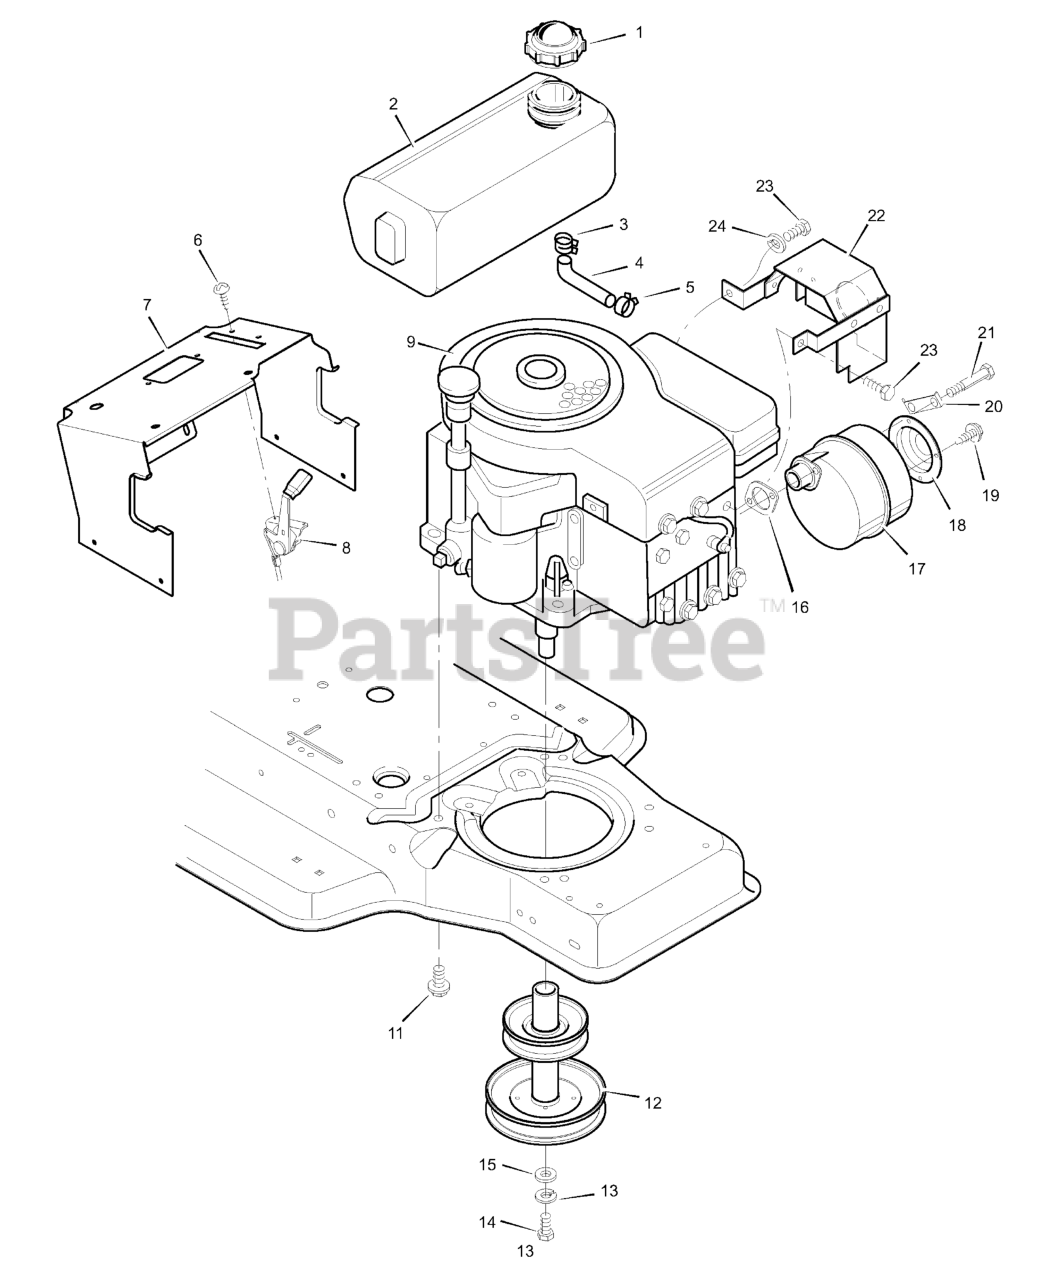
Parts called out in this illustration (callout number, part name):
1	Fuel Cap
2	Fuel Tank
3	Hose Clamp
4	Fuel Line
5	Hose Clamp
7	Support, Dash
8	Throttle Control
9	Engine *
11	Bolt, Engine Mount
12	Stack Pulley Assembly
13	Lockwasher
14	Bolt, Hex
16	GASKET, Exhaust
17	Muffler
18	Deflector, Muffler
20	Lock, Screw
22	Shield, Heat
23	Bolt
